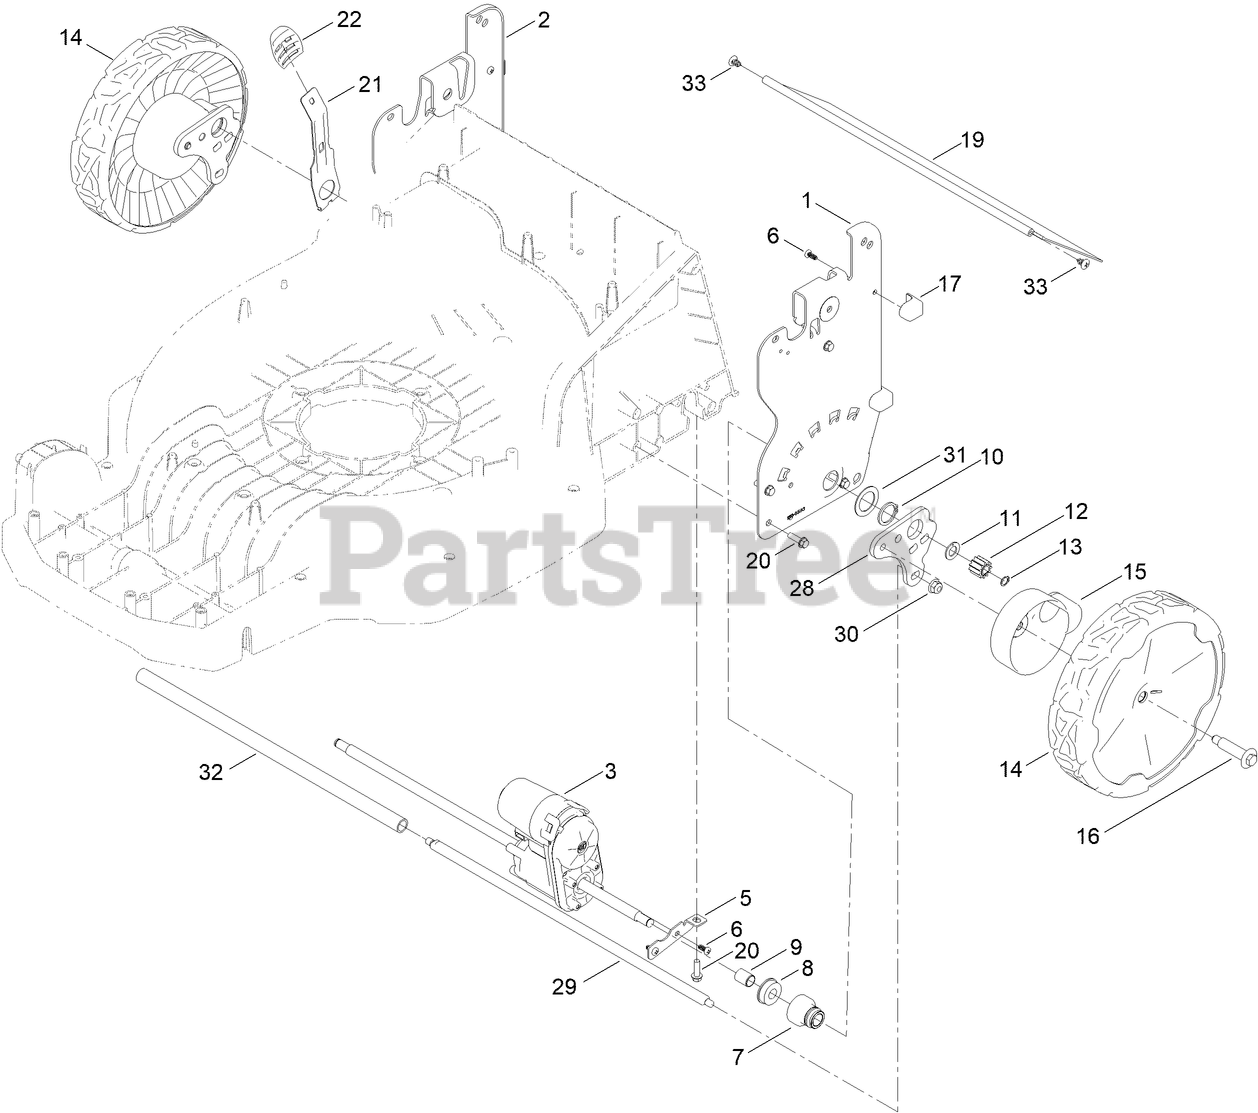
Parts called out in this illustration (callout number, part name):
1	PLATE-HOC, LH
2	PLATE-HOC, RH (2 HOLE)
3	TRANSMISSION-ELECTRIC, ME312
5	BRKT-TRANSMISSION
6	SCREW-PLASTITE
7	RETAINER-BEARING, HOC
8	BEARING-BALL
9	BUSHING-SLEEVE
10	RING-RETAINING
11	WASHER-THRUST
12	GEAR-PINION, 11T
13	RING-RETAINING, EXTERNAL
14	ASM-9.65" WHEEL, GEARED
15	ASM-COVER, GEAR
16	WHEEL BOLT
17	PAD-SMART STOW
19	SHIELD-TRAILING
20	SCREW-HWH
21	ARM-SPRING
22	KNOB-LEVER, HOC
28	BRKT-PIVOT, REAR
29	ROD-CONNECTING, REAR
30	NUT-HF, NI
31	WASHER-FLAT
32	ROLLER-STRIPER
33	SCREW-THD
